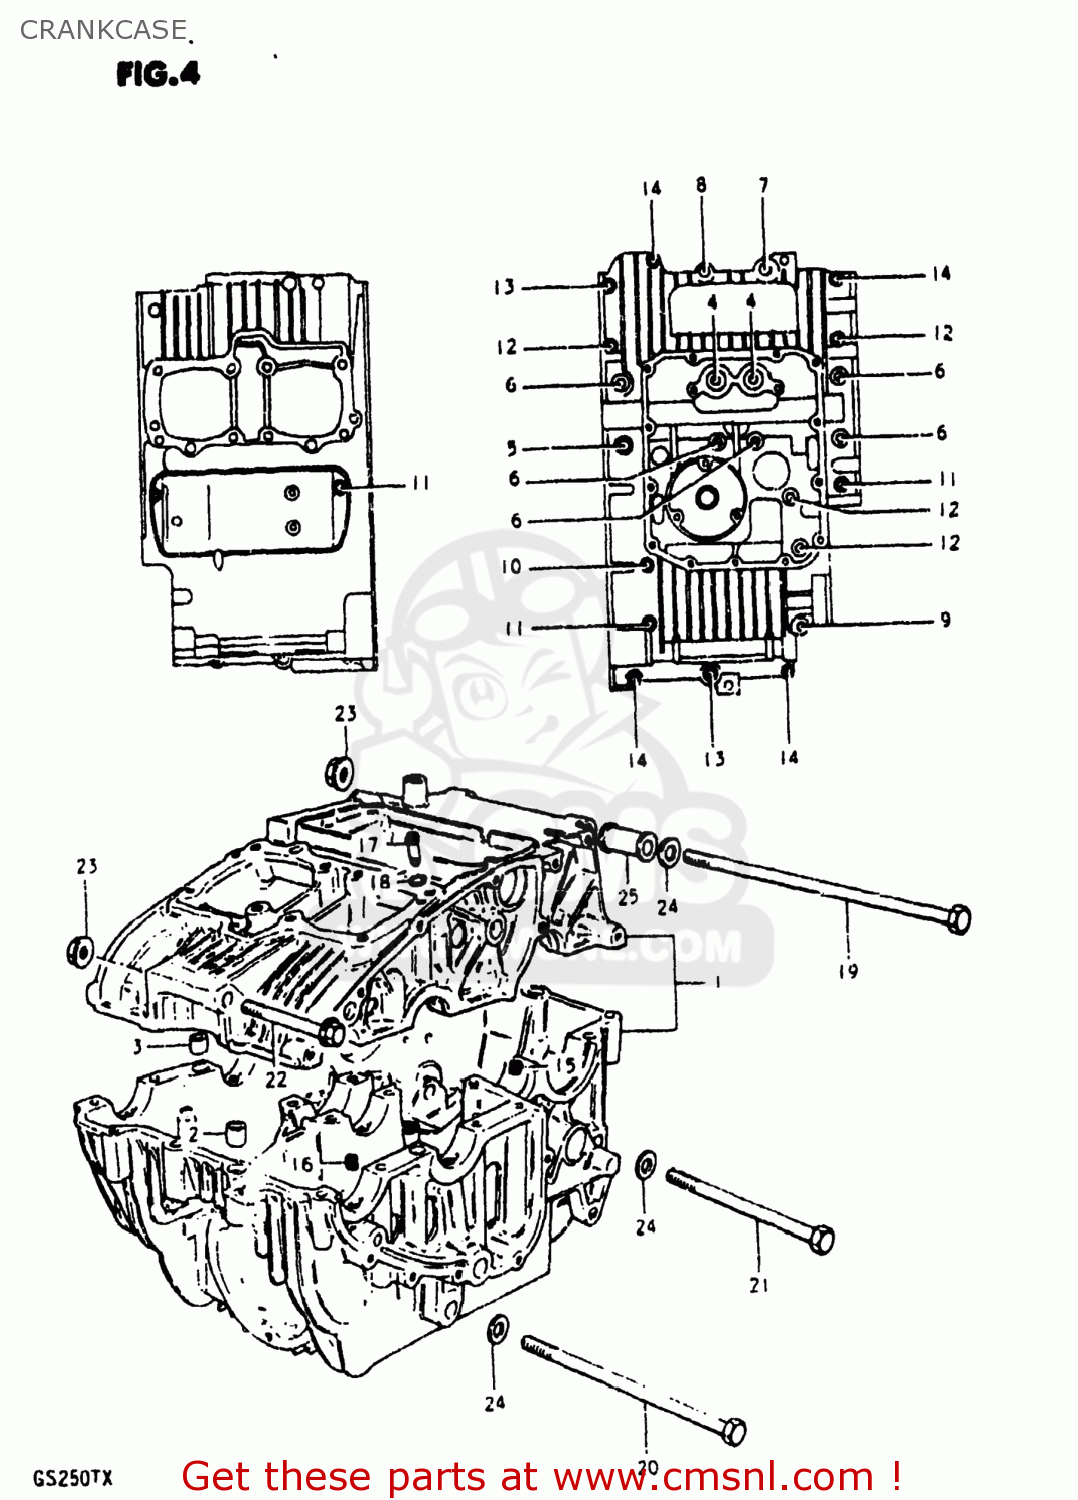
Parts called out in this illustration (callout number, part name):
1	CRANKCASE SET
2	PIN(10.4X13X22)
3	PIN (11X20)(SUS)
4	BOLT
5	BOLT
6	BOLT
7	BOLT 8X65
8	BOLT
9	BOLT (8X40)
10	BOLT
11	BOLT
12	BOLT (6X90)
13	BOLT (6X60)
14	BOLT,UNDER
15	JET,AIR(100)
16	JET,AIR
17	JET,AIR
18	O-RING
19	BOLT 10X250
20	BOLT
21	BOLT 10X160
22	BOLT
23	NUT
24	WASHER
25	SPACER,ENGINE MOUNT
